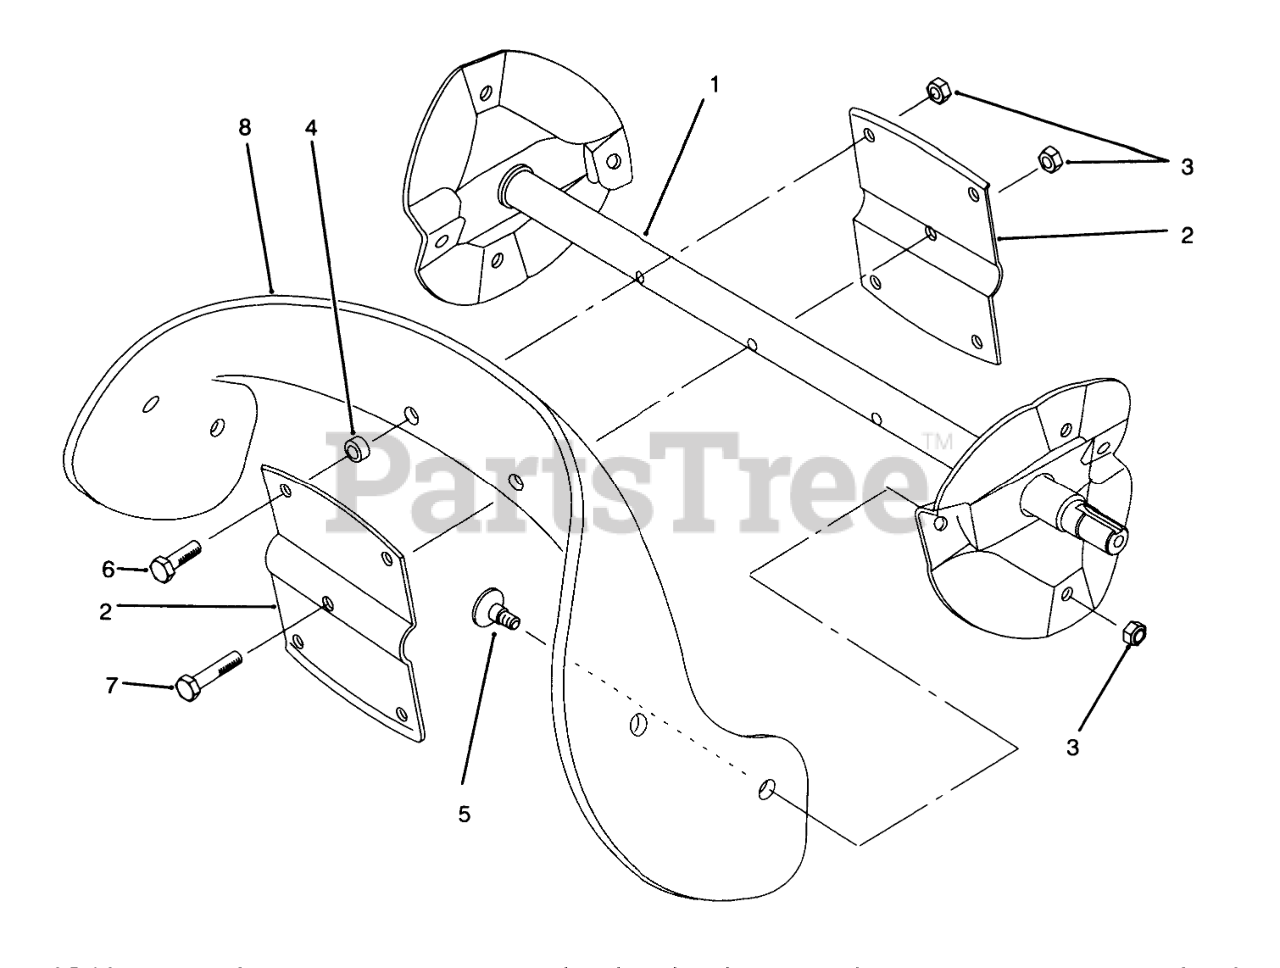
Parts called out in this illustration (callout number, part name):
1	Wa-Rotor
2	Rotor
3	NUT-LOCK, NI
4	SPACER-BLADE, ROTOR
5	SCREW
6	SCREW-HH
7	SCREW-HH
8	Blade-Rotor
